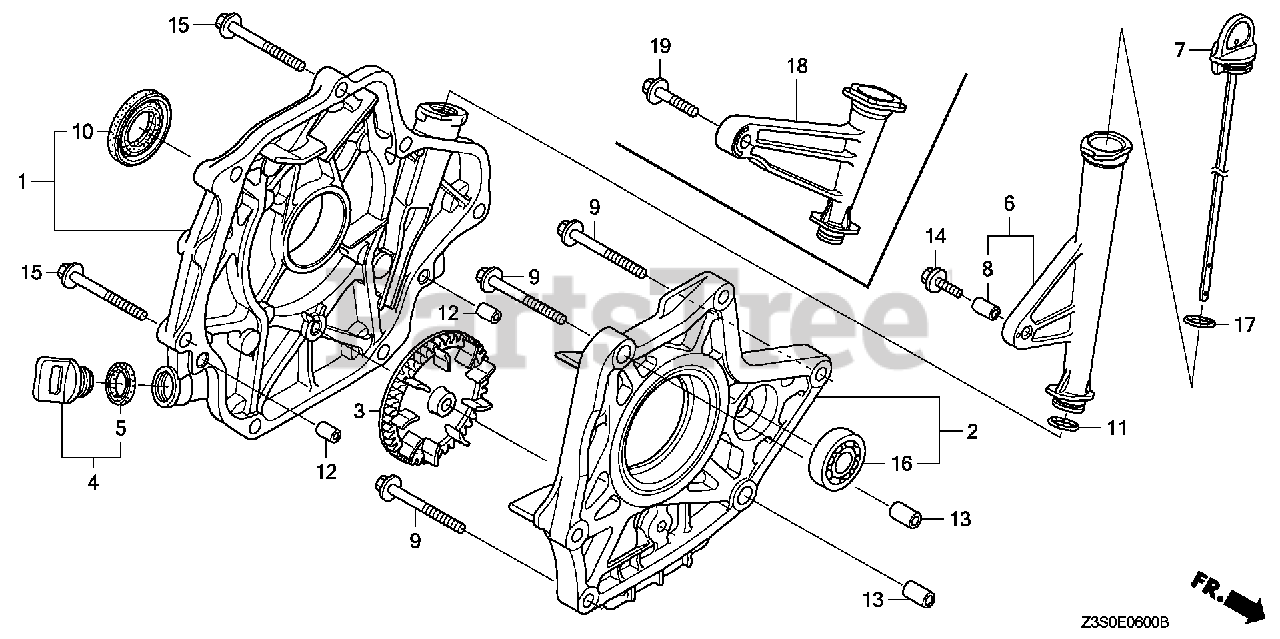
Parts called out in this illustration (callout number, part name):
1	COVER ASSY., CRANKCASE
2	HOLDER, BEARING
3	GEAR, SLINGER
4	CAP ASSY., OIL FILLER
5	GASKET, OIL FILLER CAP
7	DIPSTICK, OIL (123.5MM)
7	DIPSTICK, OIL (221.5MM)
9	BOLT, FLANGE (8X45)
10	OIL SEAL (35X52X8)
11	O-RING (20.8X2.4)
12	PIN, DOWEL (8X14)
13	PIN, DOWEL (10X16)
15	BOLT, FLANGE (8X35)
16	BEARING, RADIAL BALL (6202)
17	O-RING (18.1X3.6)
18	EXTENSION, OIL FILLER
19	BOLT, FLANGE (8X28)
